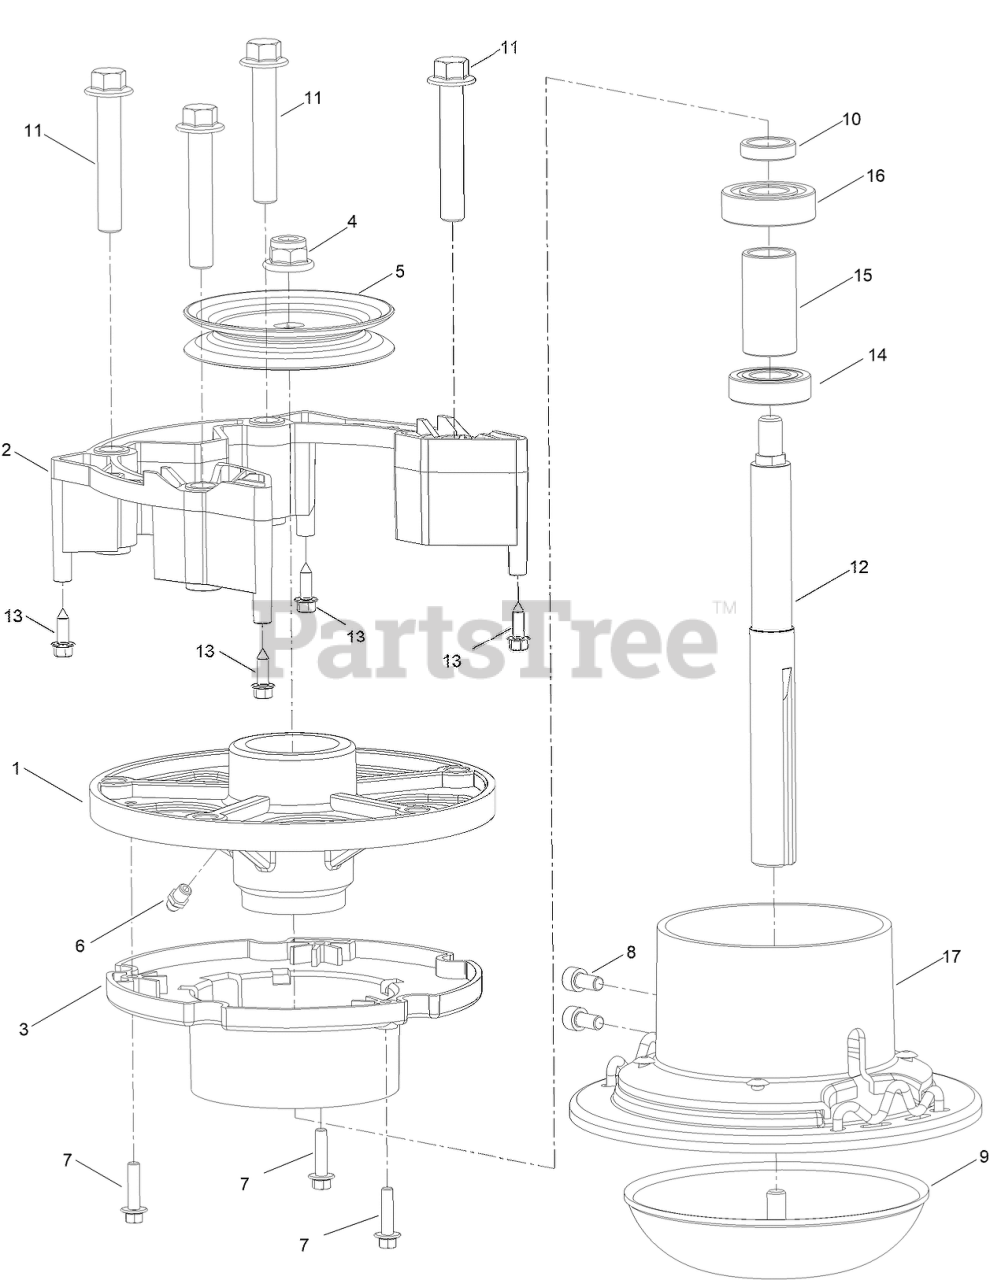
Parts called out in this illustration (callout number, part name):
1	HOUSING-JACKSHAFT, UPPER
2	SPACER-HEAD, CUTTING
3	HOUSING-TRIMMER, LOWER
4	NUT-HEX
5	PULLEY-DRIVE
6	FITTING-GREASE
7	SCREW-HHF
8	SCREW-SHCS
9	HEIGHT GUIDE ASM
10	SPACER
11	SCREW-HHF
12	SHAFT-TRIMMER
13	SCREW-PHWH
14	BEARING-BALL
15	SPACER-TRIMMER
16	BEARING-BALL
17	STRING WRAP ASM
